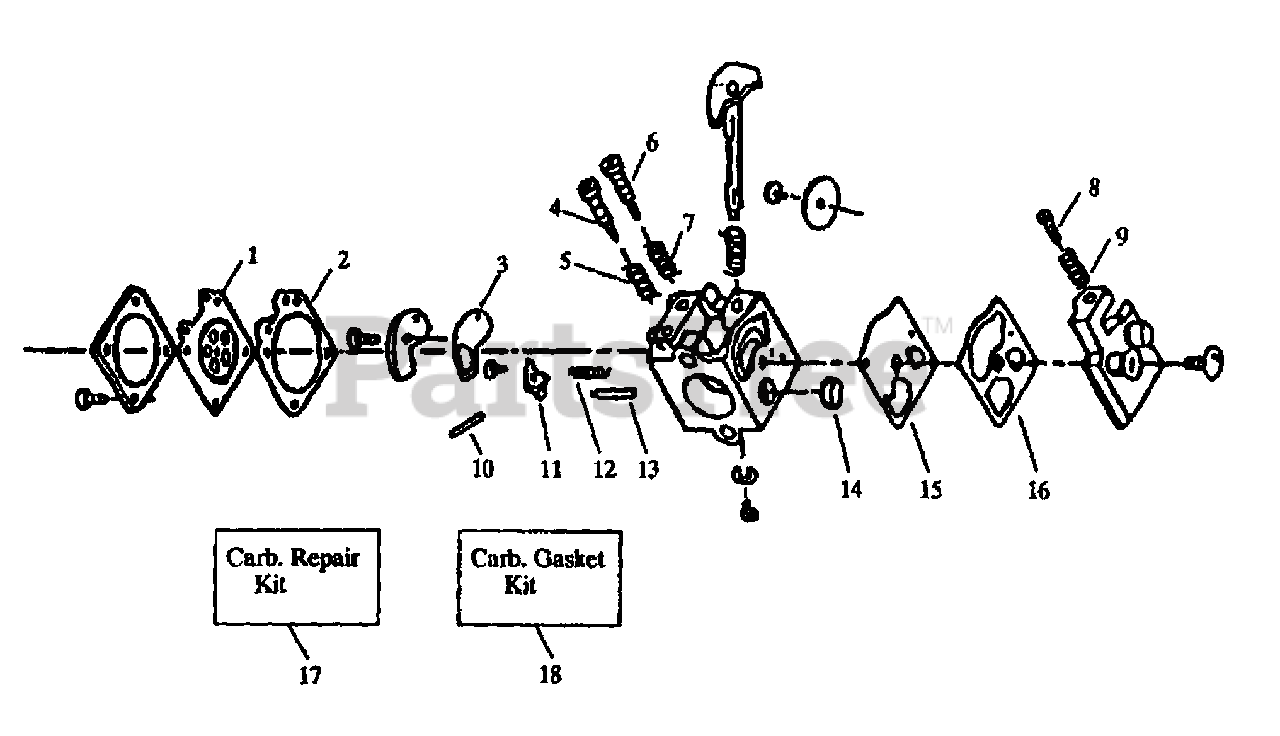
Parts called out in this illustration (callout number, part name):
1	Metering Diaphragm
2	Metering Diaphragm Gasket
3	Circuit Plate Gasket
4	Hi Speed Needle
5	Hi Speed Needle Spring
6	Idle Needle
7	Idle Needle Spring
8	Idle Speed Screw
9	Idle Speed Spring
10	Metering Pin
11	Metering Lever
12	Metering Lever Spring
13	Inlet Needle Valve
14	Inlet Screen
15	Pump Diaphragm
16	Pump Gasket
17	Carb. Kwik Repair Kit
18	Carb. Gasket/Diaphragm Kit
